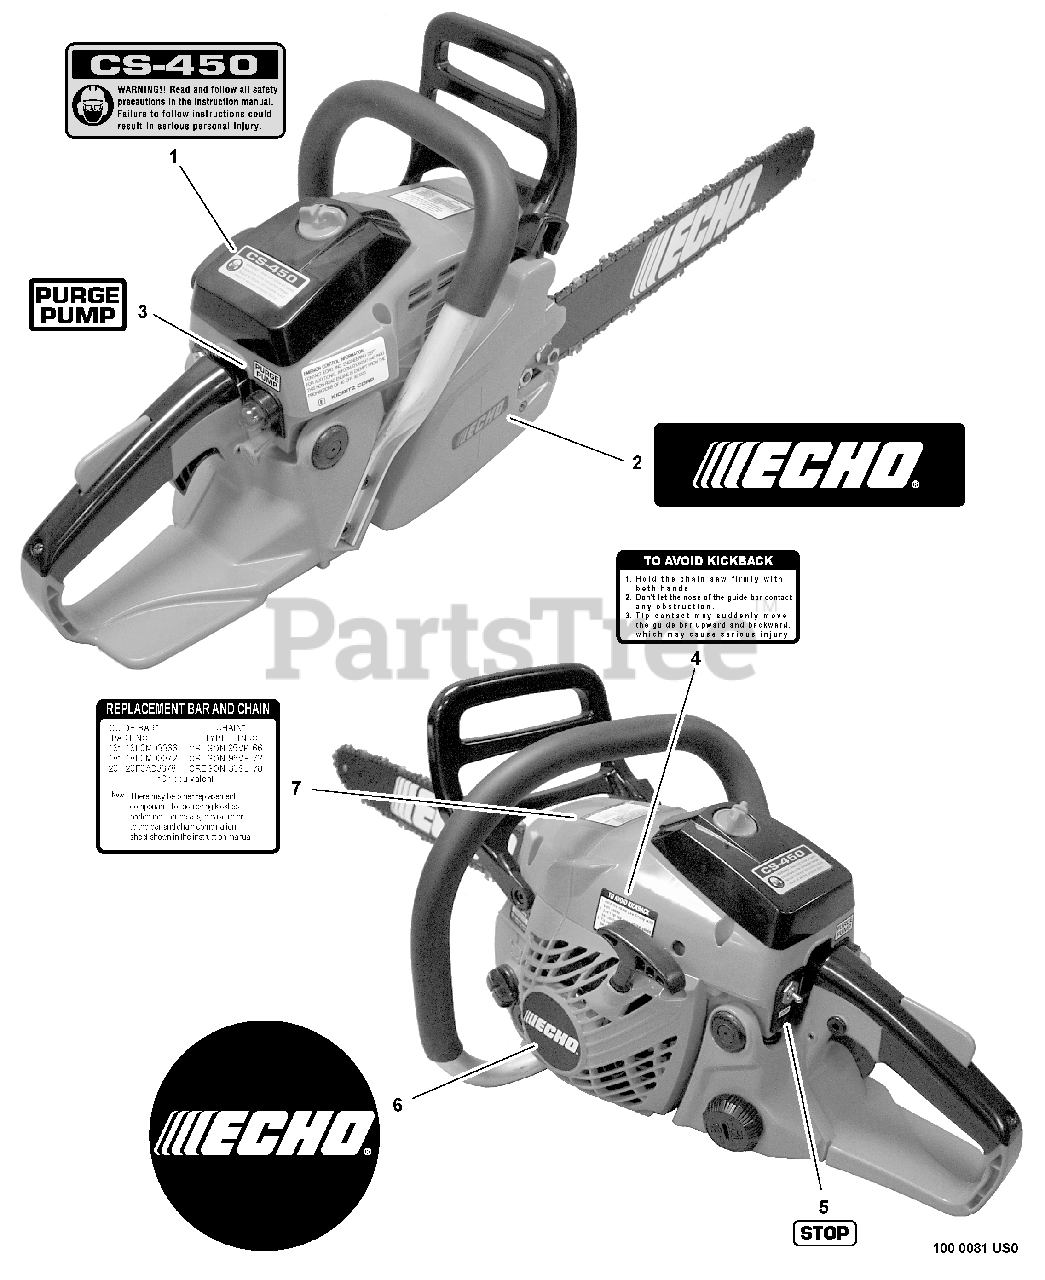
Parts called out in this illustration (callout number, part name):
1	LABEL - MODEL CS-450
2	LABEL - ECHO
3	LABEL - PURGE PUMP
4	LABEL - KICK BACK
5	LABEL - STOP
6	LABEL - ECHO
7	LABEL - BAR & CHAIN
